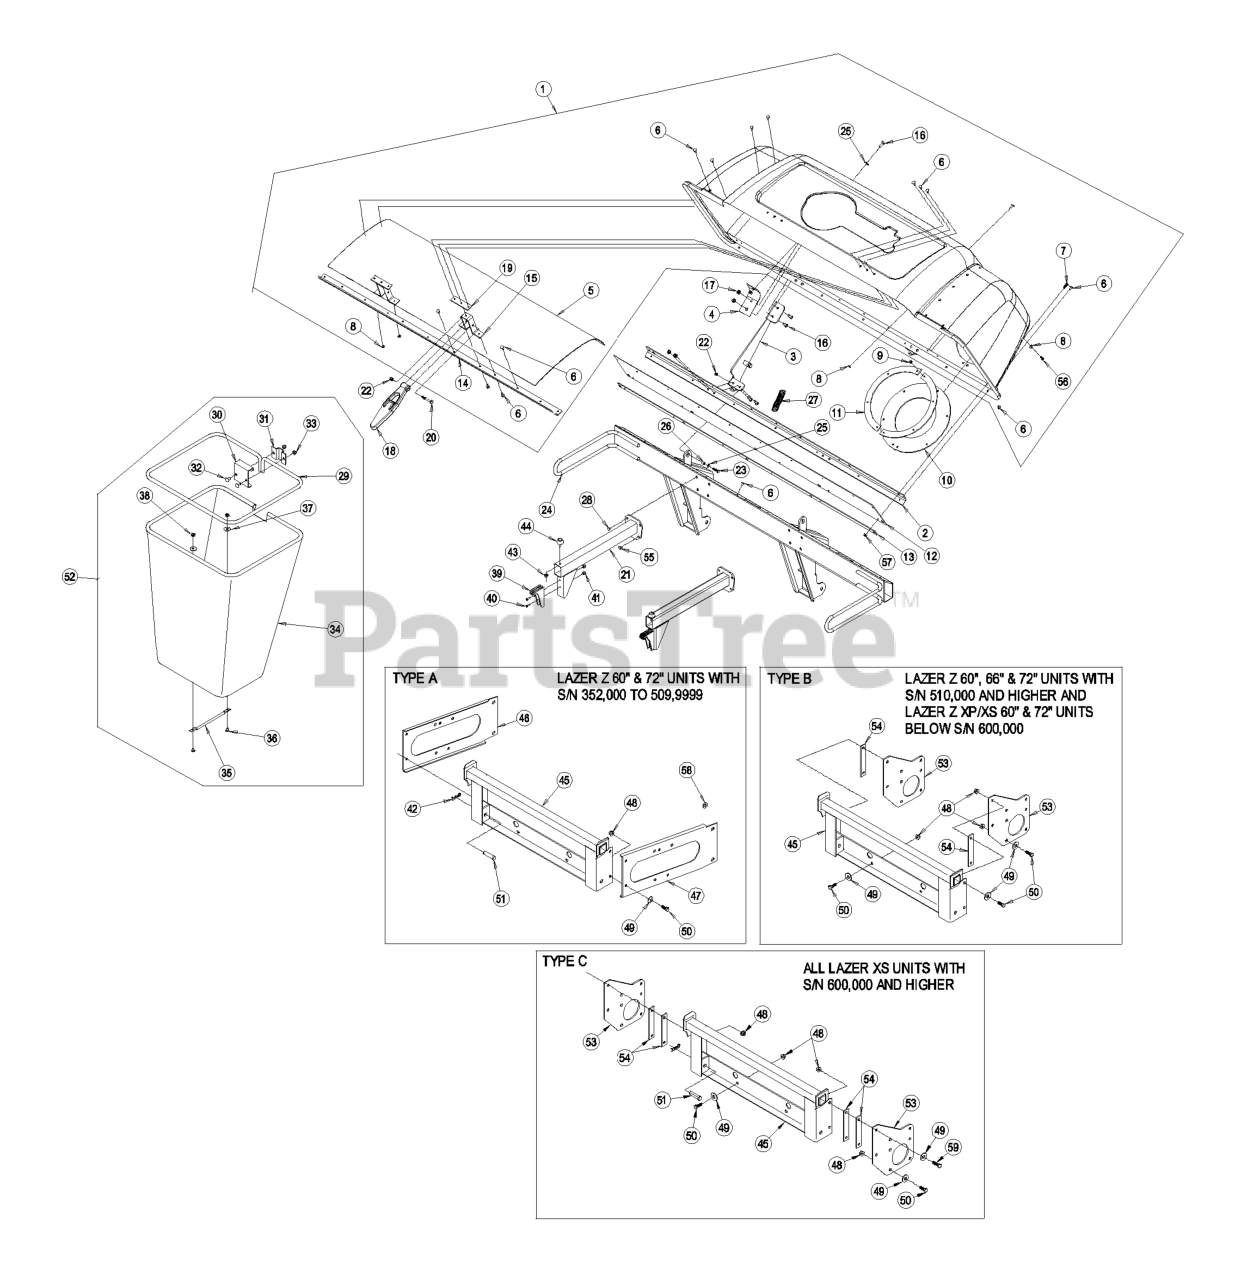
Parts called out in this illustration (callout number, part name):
1	ASM, HOOD
2	STIFFENER-BAGGER, TOP
3	HINGE ASM
4	REINFORCEMENT-HOOD, BAGGE
5	SCREEN-BAGGER
6	RIVET-BLIND
7	SCREW-HEAD, TRUSS
8	WASHER-FLAT
9	NUT-LOCK, NI
10	SEAL-TUBE
11	CLAMP-SEAL
12	SEAL-HINGE
13	PLATE-BACKING
14	SUPPORT-SCREEN
15	BRACKET-MOUNT
16	SCREW-HH
19	PLATE-LATCH, REINFORCEMEN
20	SCREW-HH
21	SUPPORT-BAG
22	NUT-LOCK, NI
23	SCREW-HH
24	UPRIGHT BAGGER ASM
25	WASHER-FLAT
27	SPRING-EXTENSION
28	SCREW-HH
29	FRAME-BAG
30	HANGER-BAG
32	BOLT-CARR
33	NUT-LOCK, NI
35	HANDLE-BAG
36	BOLT-CARR
38	NUT-LOCK, NI
40	SCREW-PPH
42	PIN-COTTER
45	MOUNT-BAGGER
46	BRACKET-FRAME, LH
47	BRACKET-FRAME, RH
48	NUT-HHF, WHIZ
49	WASHER-BELLEVILLE
50	SCREW-HH
51	PIN-CLEVIS
53	PLATE-MOUNT, BAGGER
54	SPACER
55	SCREW-HSBH
56	SCREW-PPH
57	NUT-LOCK, SIDE
58	SPACER
59	SCREW-HH
